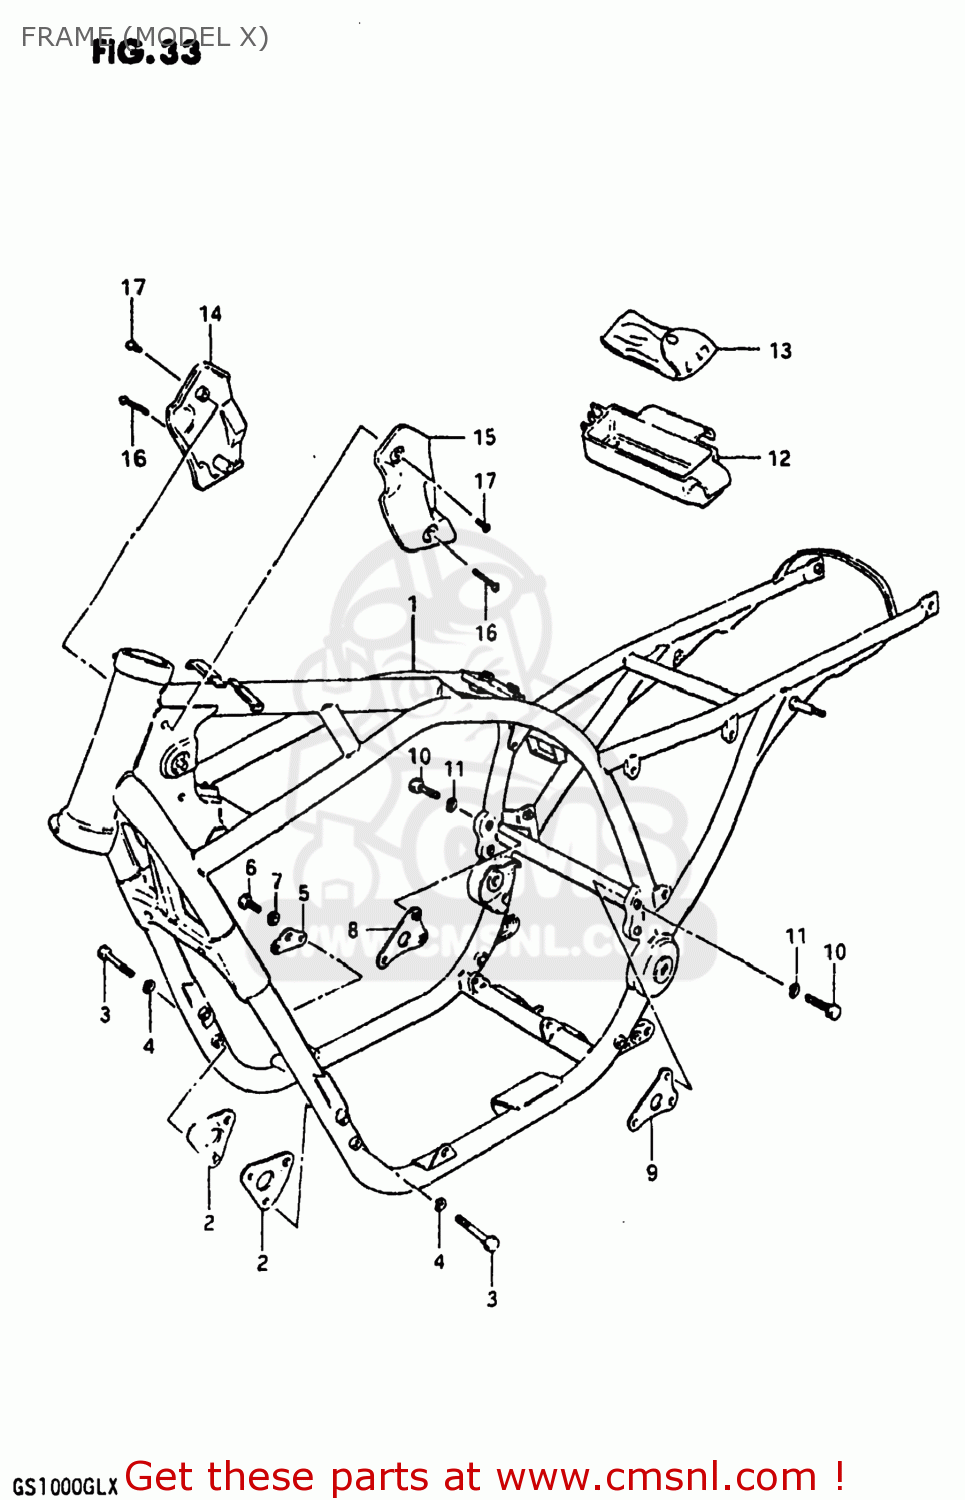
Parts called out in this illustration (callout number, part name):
1	FRAME
2	PLATE,ENGINE MOUNTING
3	BOLT
4	LOCK WASHER
5	PLATE,ENGINE MOUNTING
6	BOLT
7	LOCK WASHER
8	PLATE,ENGINE MOUNTING
9	PLATE,ENGINE MOUNTING
10	BOLT 8X40
11	LOCK WASHER
12	HOLDER,TOOL
13	TOOL SET
14	COVER,FRAME HEAD,RIGHT
15	COVER,FRAME HEAD,LEFT
16	SCREW, LOWER
17	SCREW
